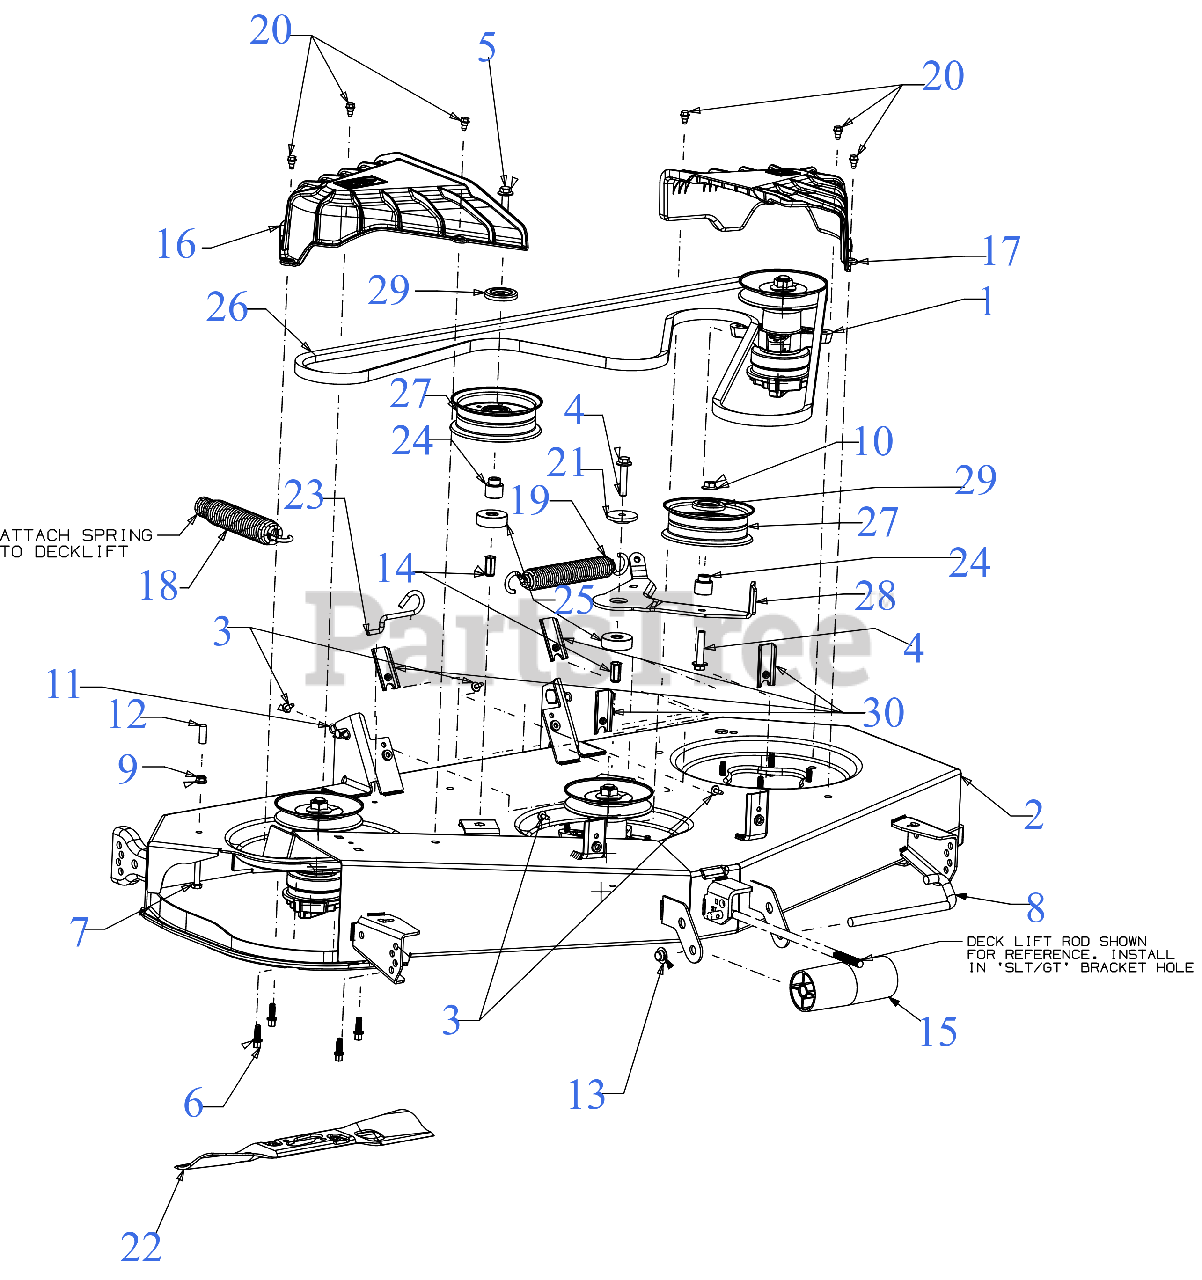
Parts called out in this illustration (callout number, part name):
1	BLADE SPINDLE ASSEMBLY
2	50" FAB DECK SHELL
3	SCREW M6-1 x .625
4	SCREW 3/8-16 x 2.0
5	SCREW 3/8-16 x 2.75 GR5
6	SCREW 5/16-18 x .875
7	SCREW 5/16-18 x 1.5 LG
8	ROLLER PIN 1/2 x 7.31
9	FLANGE LOCK NUT 5/16-18
10	FLANGE LOCK NUT
11	BOW TIE COTTER PIN
14	NUT RIVET 3/8-16
16	SPINDLE COVER (RH)
17	SPINDLE COVER (LH) (YELLOW)
18	LIFT ASSIST SPRING (LARGE)
19	SPRING 1.25" DIA x 8.5" LONG
20	SHOULDER SCREW 1/4-20 x .50
21	SHOULDER SPACER
22	50" HIGH-LIFT FASTATTACH BLADE
22	Cub Cadet 50"/54" DETHATCHING BLADE SET
22	50" FASTATTACH XTREME MULCH BLADE
22	50" LOW-LIFT SAND FASTATTACH BLADE
23	DECK SPRING HOOK
24	SHOULDER SPACER
25	SPACER .385ID x 1.75OD x .585THK
26	V-BELT B SEC x 134
26	Cub Cadet 50" DECK BELT
26	Genuine Factory Parts 50" DECK BELT
26	IDLER PULLEY 4.50" DIA
28	IDLER PIVOT BRACKET
29	IDLER PULLEY CAP
